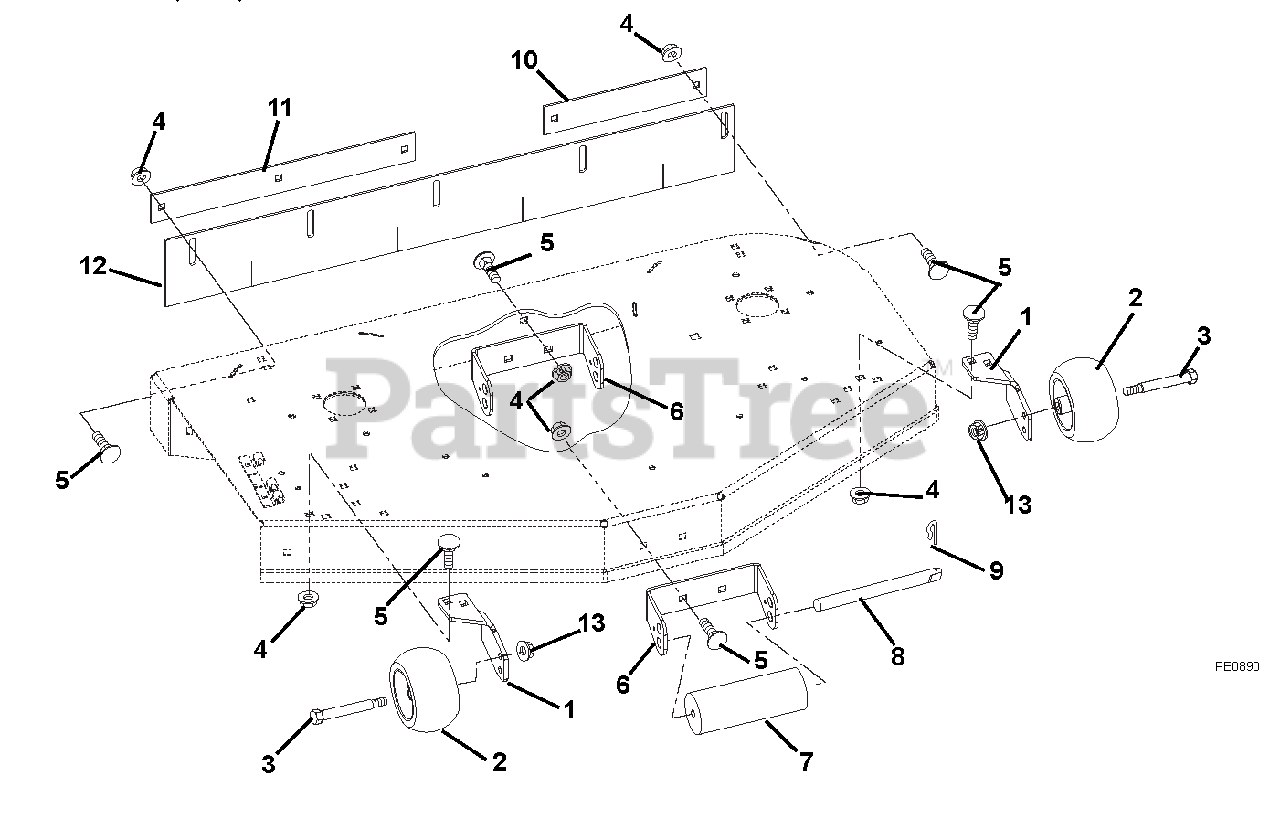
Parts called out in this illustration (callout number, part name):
1	BRACKET, ANTI SCALP
2	WHEEL 5 X 3
3	BLT-SHLDR .38-16X2.50 HWH G5
4	@NUT-LK-NYL-FLG .38-16 YWZC
5	@BLT-RDHDSQNK .38-16X1.00 G5YZ
6	BRACKET, ROLLER MOUNT
8	PIN, ROLLER
9	PIN, SPRING CLIP
10	BAR, LH RETAINER STRIPER
11	BAR, RETAINING STRIPPER-44"
11	BAR, RETAINING STRIPPER-52"
11	BAR, RETAINING STRIPER-40"
12	STRIPER, RUBBER-44"
12	STRIPER, RUBBER-48"
12	STRIPER, RUBBER-40"
13	@NUT-LK-TOP-FLG .38-16 YWZC
